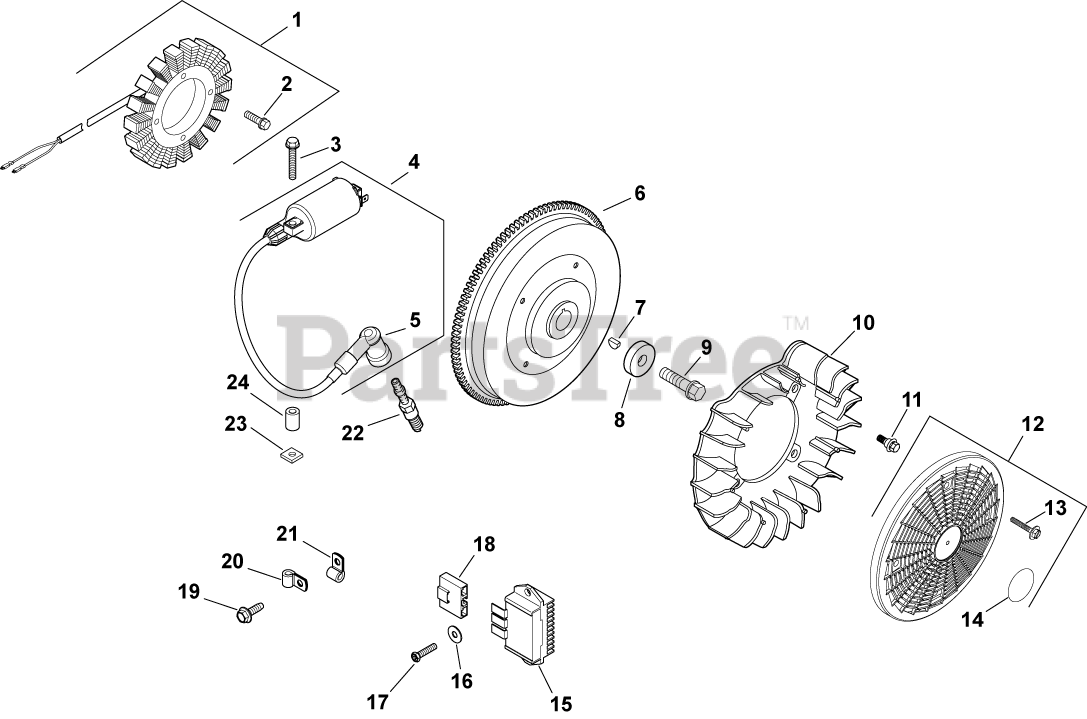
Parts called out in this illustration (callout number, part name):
1	KIT, 25 AMP STATOR ASSY.
2	SCREW, WSH HD TAP #10-24X1"
3	SCREW,WSH HD TAP 1/4-14X1 1/2"
4	COIL, IGNITION
5	BOOT, SPARK PLUG
6	FLYWHEEL, PAINTED-USE 24 025 23-S
7	KEY, 3/16" X 5/8"
8	WASHER, FLAT 13/32"
9	SCREW, FLG M10X1.5X45 - (#25086361S)
11	BOLT, SHOULDER
12	KIT, GRASS SCREEN
13	SCREW, FLG SEMS M4X.7X25
14	DECAL, GRASS SCREEN USE 24 113 499-S
15	REG-RECTIFIER (25 AMP)-USE 25 403 21-S
16	WASHER, FLAT 3/16"
17	SCREW, PHL HD #11-16X7/8"
18	CONNECTOR, BODY (KM)-USE 25 155 41-S
19	SCREW,FLG THD FRM M5X0.8X16-(#25086398S)
20	CLAMP, INSULATED
21	CLIP, TUBE & WIRING (KM)
22	PLUG, SPARK (STD)
23	NUT, PLASTIC (KM)-USE 25 100 37-S
